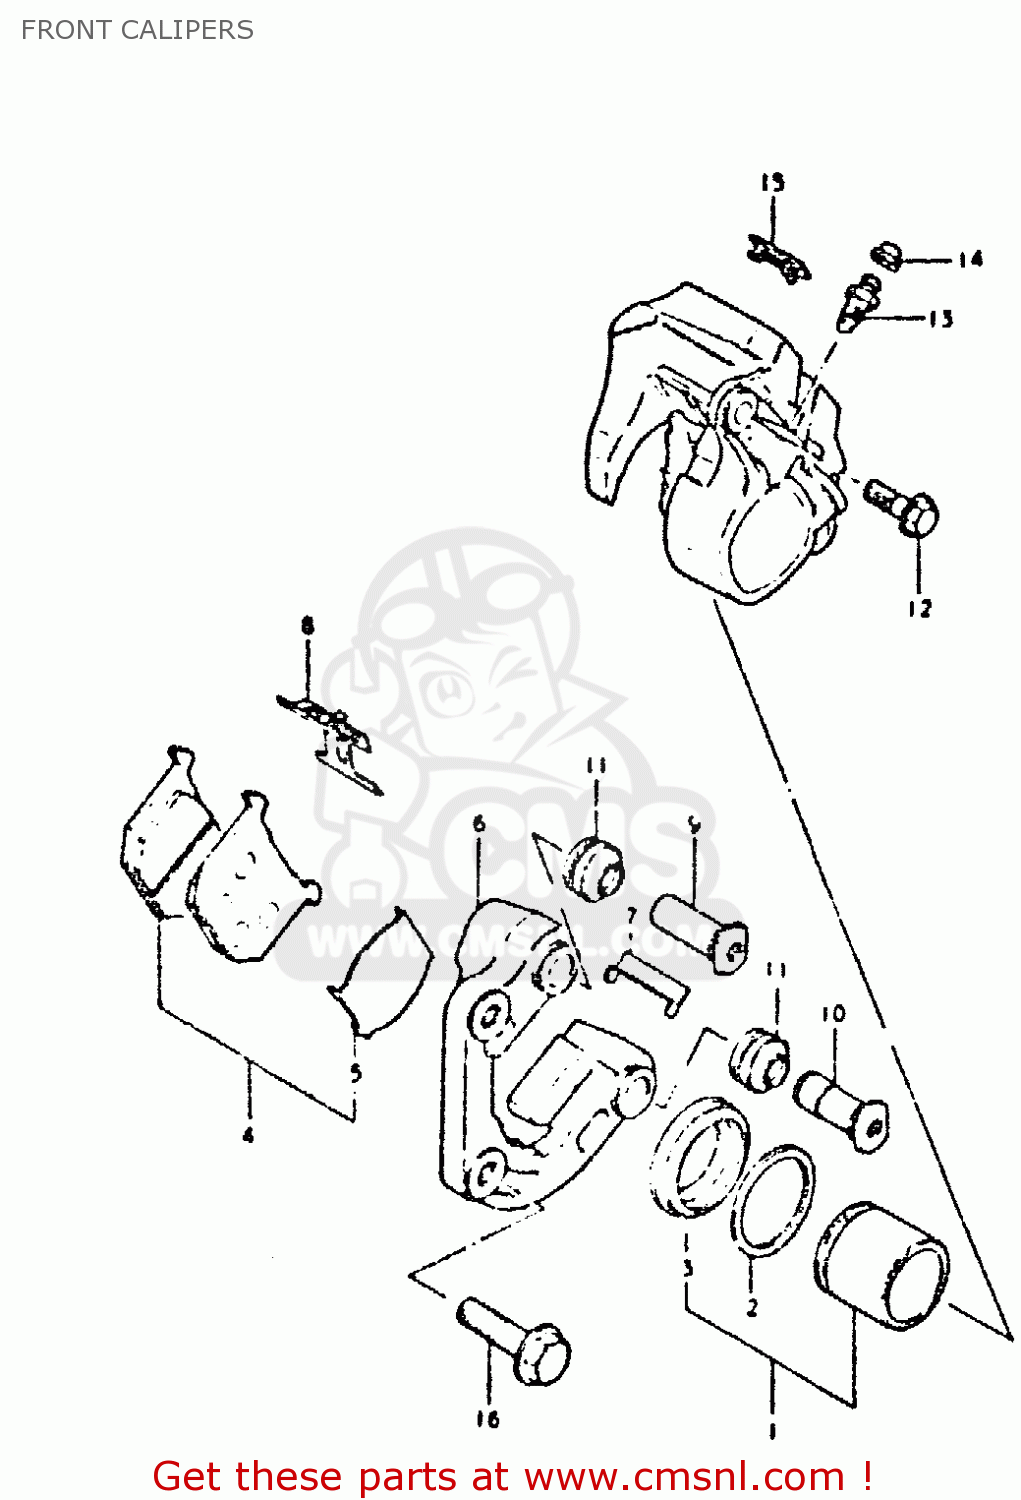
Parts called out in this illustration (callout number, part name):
1	PISTON SET
2	SEAL,FR CALIPE
3	BOOT,PISTON
4	PAD SET (MCA)
5	SHIM,PAD
6	CARRIER,CALIPER,LEFT
7	GUIDE,PAD
8	SPRING,PAD
9	AXLE NO.1
10	AXLE NO.2
11	BOOT,AXLE
12	BOLT,CALIPER HOUSING
13	BLEEDER
14	CAP,BREATHER
15	COVER,INDICATOR
16	BOLT(10X37)
